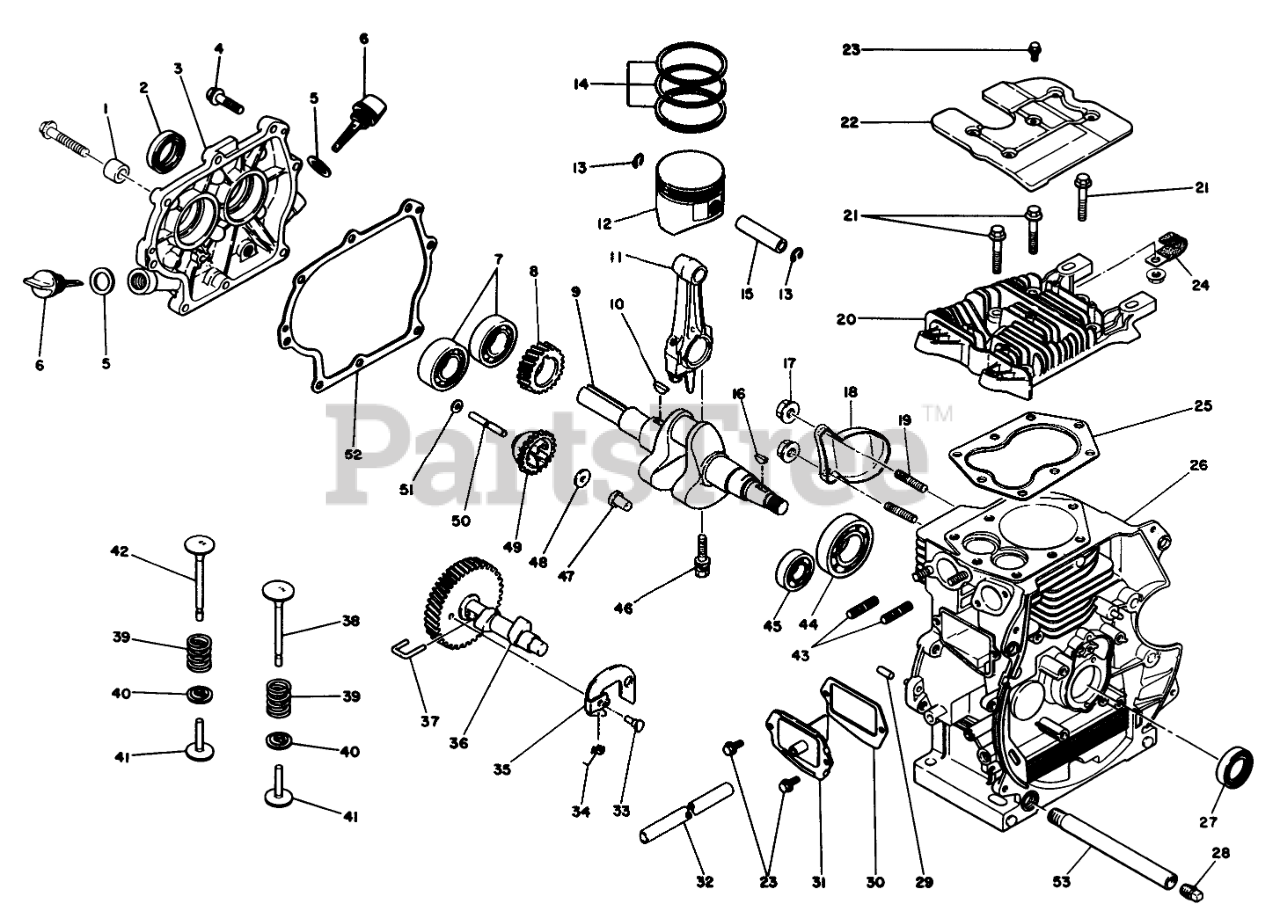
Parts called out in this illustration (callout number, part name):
1	SPACER
2	OIL SEAL
3	COVER-CRANKCASE
5	GASKET
6	Gauge-Oil (Incl. Ref. #5)
7	BEARING
8	CRANKSHAFT GEAR
9	CRANKSHAFT
11	Connecting Rod Assembly (Std.) (Incl. Ref #46)
12	Piston Assembly (Std.) (Incl. Ref. #15)
14	PISTON RING SET
15	PIN - PISTON
18	COVER
20	CYLINDER HEAD
22	COVER-HEAD
24	CLAMP
25	HEAD GASKET
26	Cylinder Block Assembly (Incl. Ref. #19, 29 & 43)
27	OIL SEAL
28	CAP-PIPE
30	GASKET=BRTHR
31	BREATHER VALVE ASM
32	BREATHER TUBE
34	SPRING
35	FLYWEIGHT
36	Camshaft Assembly (Incl. Ref. #34-36 & 38)
38	INTAKE VALVE
39	VALVE SPRING
40	RETAINER VALVE
41	TAPPET
42	EXHAUST VALVE
44	BEARING
45	BEARING
46	CONNECTING ROD BOLT
47	SLIDER-GOV
48	SPACER
49	Governor Gear Assembly (Incl. Ref. #47)
50	SHAFT-GOV.
51	WASHER
52	CRANKCASE GASKET
53	DRAIN TUBE
